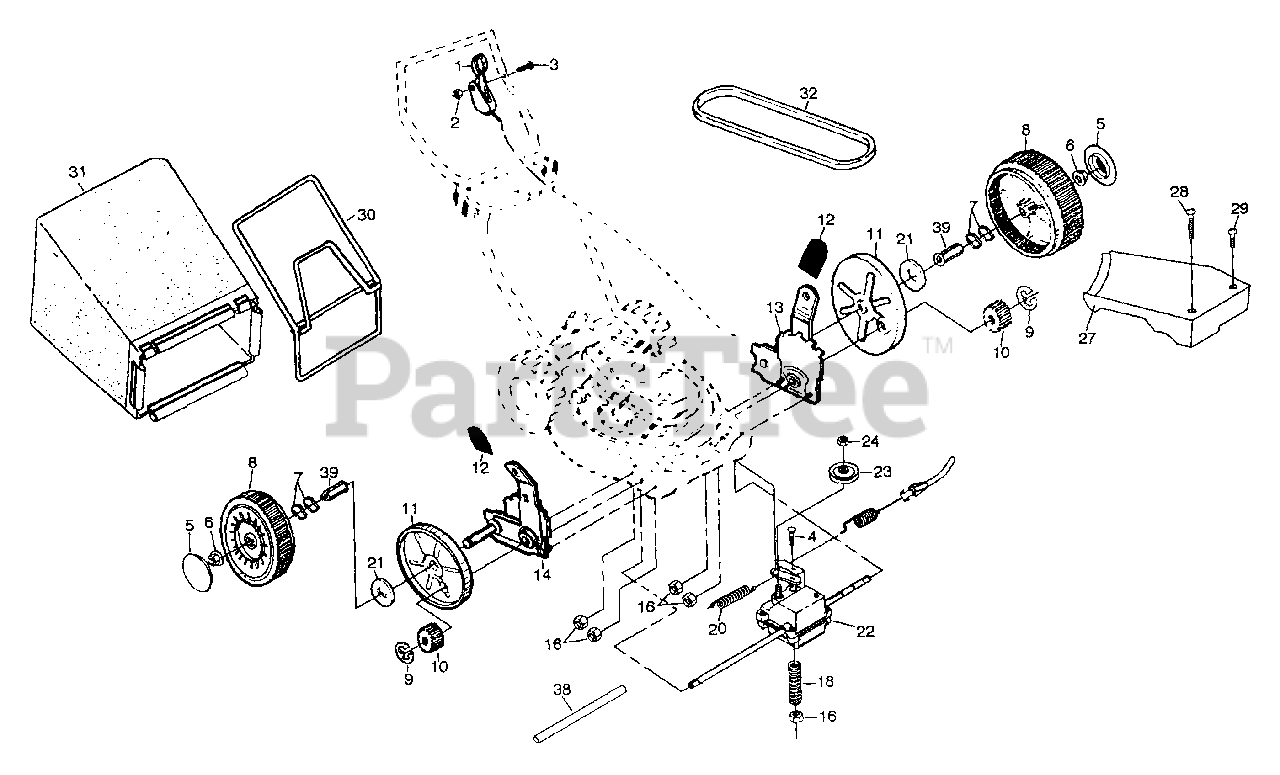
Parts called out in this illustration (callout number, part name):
1	Drive Control (AYP part number)
2	Locknut 1/4-20 (AYP part number)
3	Hex Washer Head Screw 3/4-20 x 2.12
4	Carriage Bolt 1/4-20 x 2 (AYP part number)
5	Hubcap (AYP part number)
6	Flanged Locknut (AYP part number)
7	Wave Washer (AYP part number)
8	Wheel & Tire Assembly
9	E-ring (AYP part number)
11	Dust Cover
12	Selector Knob (AYP part number)
13	Wheel Adjuster Assembly (Left) (AYP part number)
14	Wheel Adjuster Assembly (Right) (AYP part number)
16	Locknut (AYP part number)
18	Spring (AYP part number)
21	Washer 1/2 x 1-1/2 x .134 (AYP part number)
22	Gear Case Assembly
23	Drive Pulley (AYP part number)
24	Locknut (AYP part number)
27	Drive Cover (AYP part number)
28	Pan Head Tapping Screw #10-24 x 2-3/4 (AYP part number)
29	Pan Head Tapping Screw #10-24 x 1-3/4 (AYP part number)
30	Catcher Frame
31	Grass Bag (AYP part number)
32	V-Belt
38	Drive Shaft Cover (AYP part number)
39	Wheel Bushing (AYP part number)
